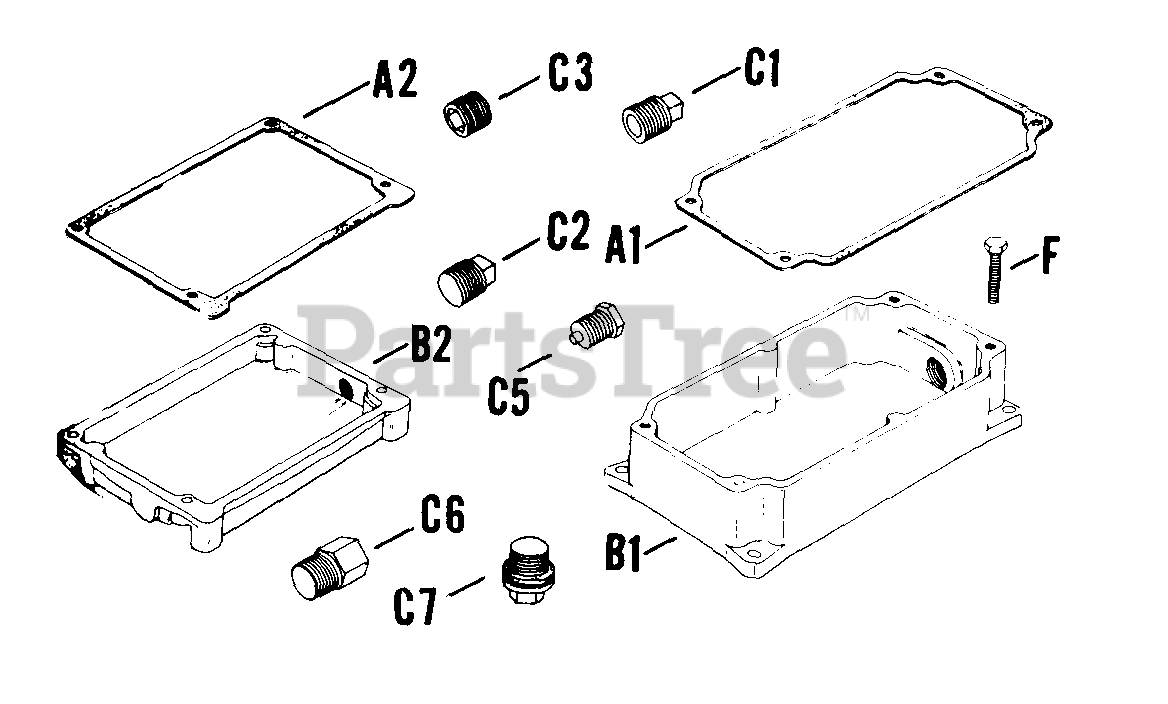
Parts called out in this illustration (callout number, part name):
A1	GASKET, OIL PAN
C1	PLUG - USE X-75-6
C2	PLUG,PIPE SQ HD 3/4" USE 25 139 56-S
